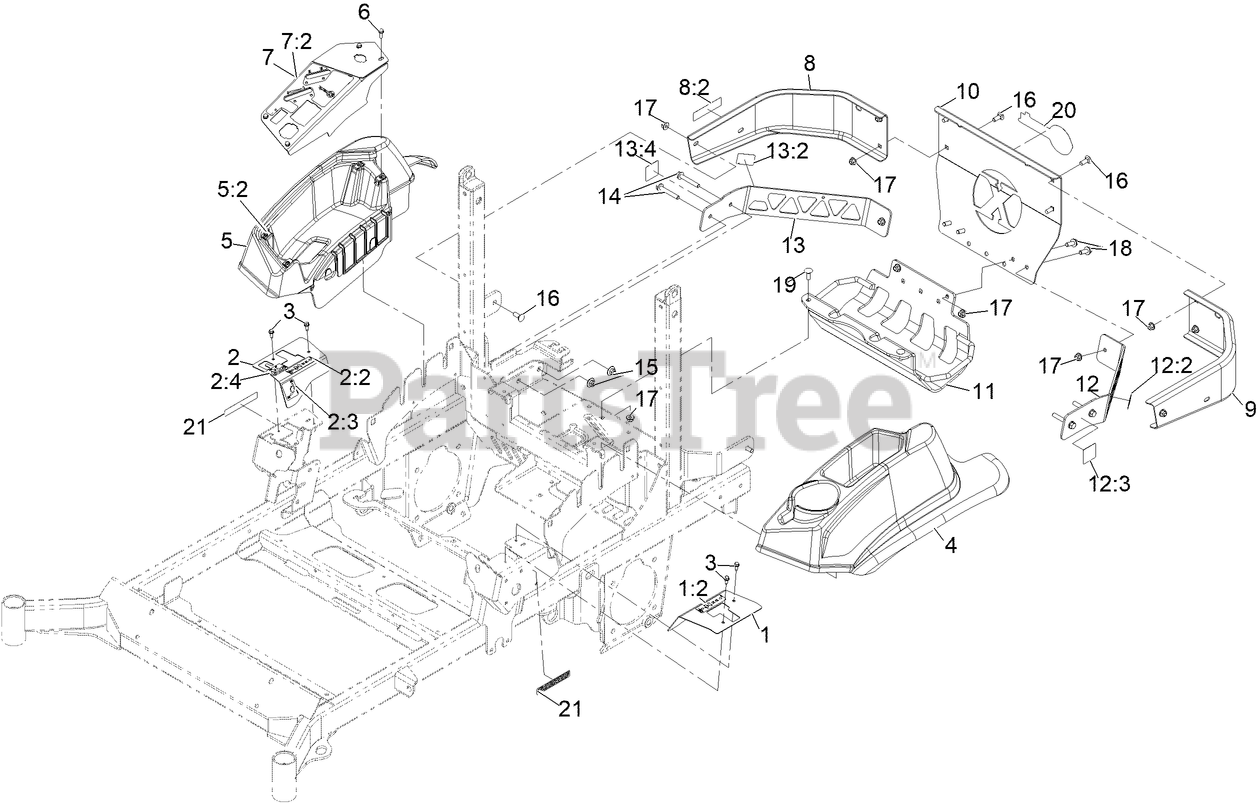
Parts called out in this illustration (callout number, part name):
1	LH MOTION CONTROL COVER ASM
1:2	DECAL-CONTROL, MOTION
2	RH MOTION CONTROL COVER ASM
2:2	DECAL-CONTROL, MOTION
2:3	DECAL-PARK BRAKE, CE
2:4	DECAL-TRANSPORT LOCK
3	SCREW-HWH
4	CONSOLE, LH AS
5	CONSOLE,RH AS ASM
6	SCREW-HWH
7	Panel-Control W/Decal
7:2	Decal-Control Panel
8	ASM, Rear Rt Bumper W/Decal
8:2	DECAL-ARRESTOR, SPARK
9	Bumper,Rear LH
10	Gaurd, Rear
11	Weld, Muffler Guard
12	ASM, Rear Lt Strap W/ Decals
12:2	DECAL-WARNING
12:3	DECAL-HAZARD, PINCHED FINGER
13	ASM, Rear Rt Strap W/ Decals
13:2	DECAL-WARNING
13:4	DECAL-HAZARD, PINCHED FINGER
14	Screw-HHF
15	Nut-Nyloc 3/8-16 Flg
16	Screw-CARR
17	NUT-HF, NI
18	SCREW-HHF
19	BOLT-CARR
20	DECAL, EXMARK LOGO
21	Decal-E-Series
